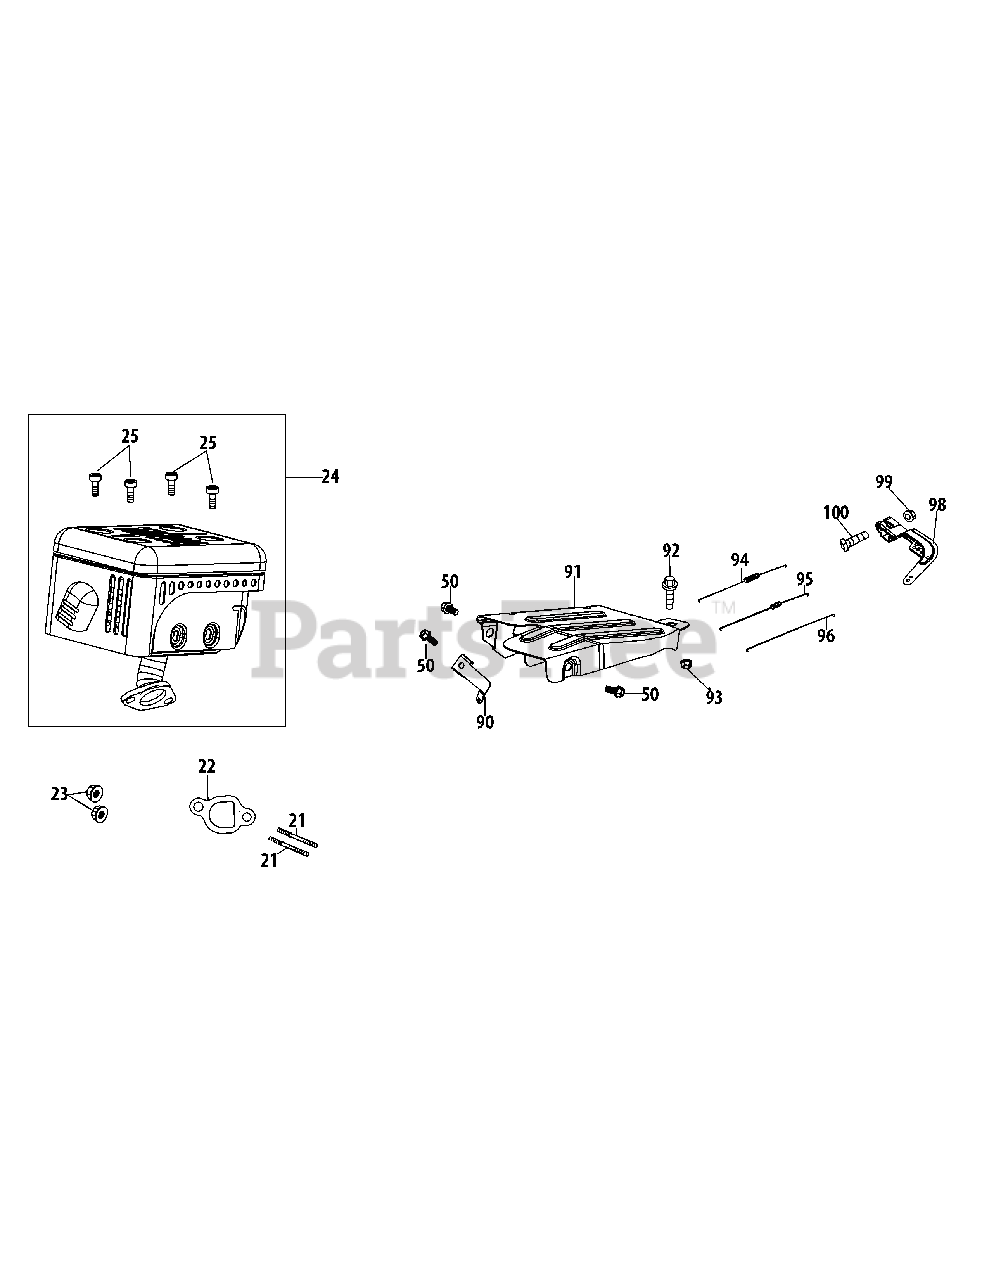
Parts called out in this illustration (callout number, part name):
21	Muffler Stud Assembly
22	Muffler Gasket
24	Muffler Assembly
25	Bolt M5×10
90	Covernor Spring Bracket
91	Governor Shield
92	Bolt M6×28
93	Nut M6
94	Governor Spring
95	Throttle Linkage Spring
96	Throttle Linkage
99	Nut M6
100	Governor Arm Bolt
